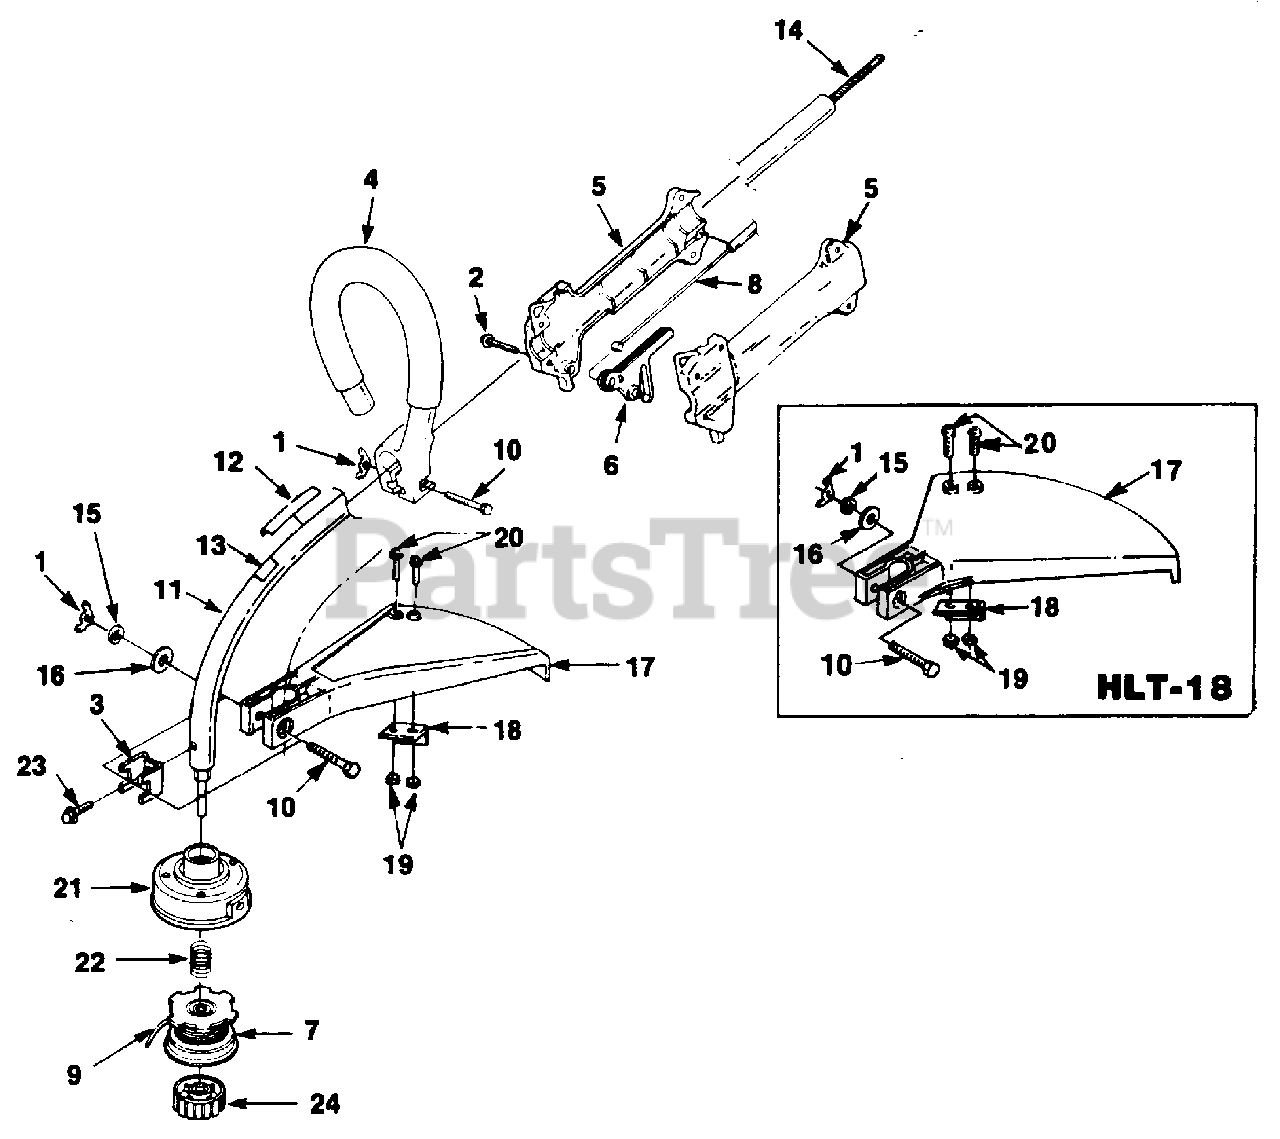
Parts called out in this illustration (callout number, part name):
1	NUT-Wing
2	SCREW- Plastite (#8 x 3/4")
3	CLAMP
4	HANDLE- Front
5	HANDLE GRIP ASSEMBLY
6	TRIGGER
7	SPOOL & STRING
9	LINE- Replacement (.095" Dia.) (1 lb.)
10	SCREW (1/4-20 x 2")
11	HOUSING-Driveshaft
13	DECAL- Warning
14	SHAFT- Flexible
15	LOCKWASHER (1/4")
16	WASHER- Flat (1/4")
17	DEFLECTOR- Grass
18	BLADE- Cut-off (HLT-16 Only)
19	NUT (10-24)
20	SCREW (10-24 x 1")
21	HOUSING & EYELET- Dual line
22	SPRING- Compression
23	SCREW (10-24 x 3/8")
24	RETAINER- Spool (R.H. Thread)
